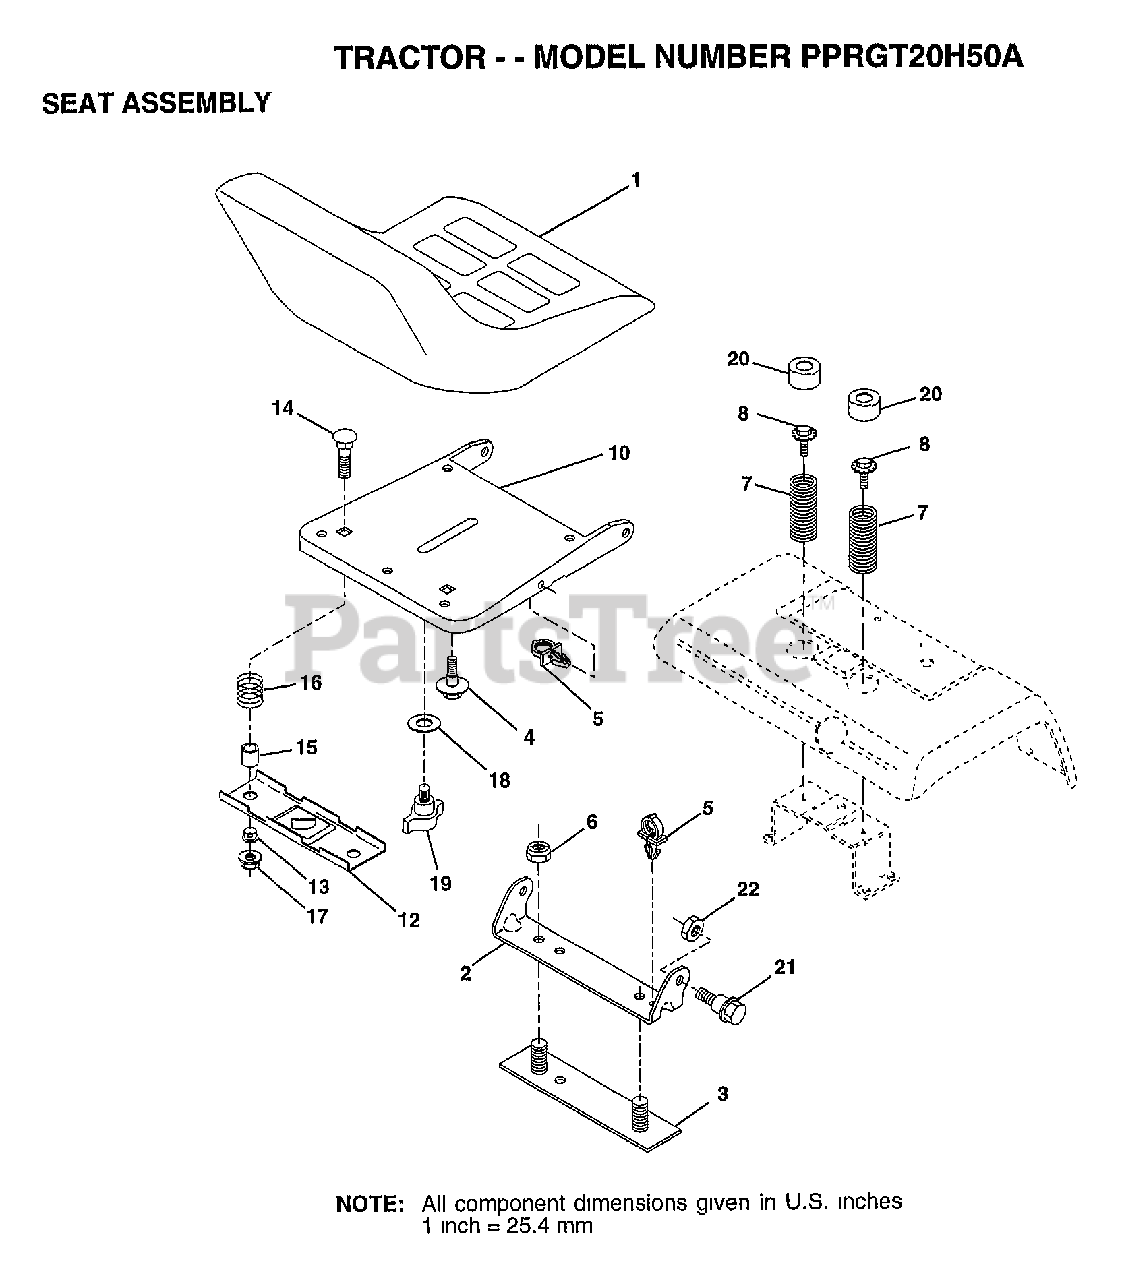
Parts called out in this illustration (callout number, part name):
2	BRACKET PVT SEAT
3	STRAP ASM FENDER
4	"BOLT,SHOULDER"
5	CLIP.PUSH-IN.HING
6	NUT
7	SPRING COMPRESSIO
8	BOLT.5/16-18.UNC
10	PAN-SEAT
12	BRKT SWITCH
13	BUSHING
14	BOLT-RD HD SQ NK
15	SPACER SPLIT
16	SPRING COMPRESSED
18	WASHER
19	KNOB.SEAT.ADJ.WINGNUT
20	CAP SPRING
21	"BOLT,SHOULDER"
22	NUT
